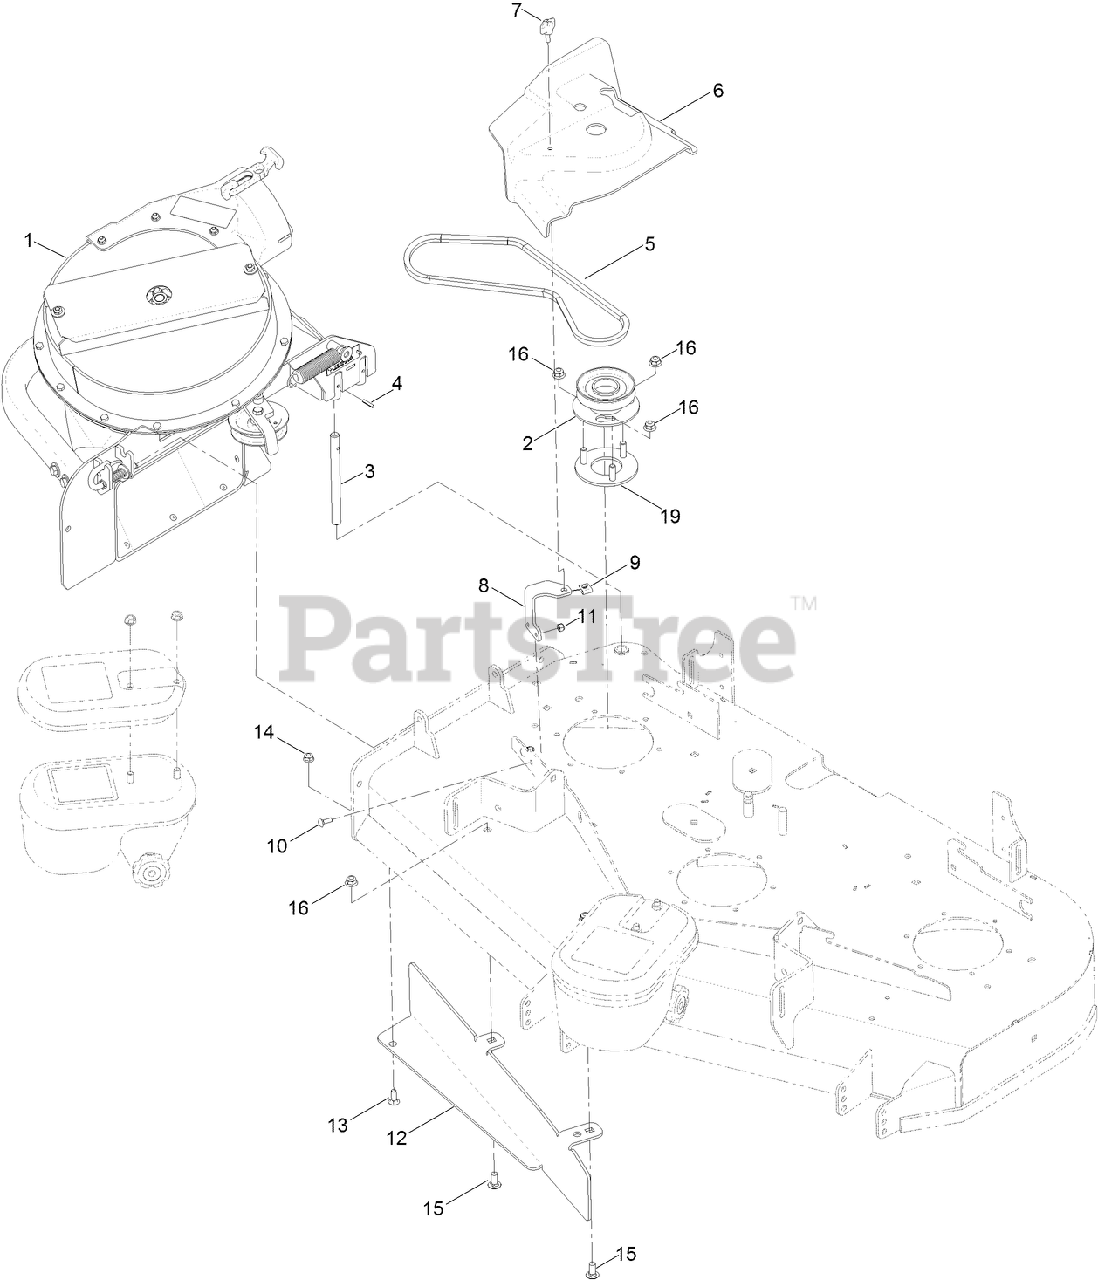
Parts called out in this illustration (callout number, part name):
1	BLOWER ASM
2	PULLEY-BLOWER
3	SHAFT-CATCHER, GRASS
4	PIN-ROLL
5	BELT-V
6	BELT-COVER
8	BRACKET-COVER, BELT
9	NUT-SPEED
10	BOLT-CARR
11	NUT-LOCK, NI
12	BAFFLE-BAGGER
13	SCREW-CARR
14	NUT-HF, NI
15	SCREW-CARR
16	NUT-HF, NI
19	MOUNT-PULLEY
